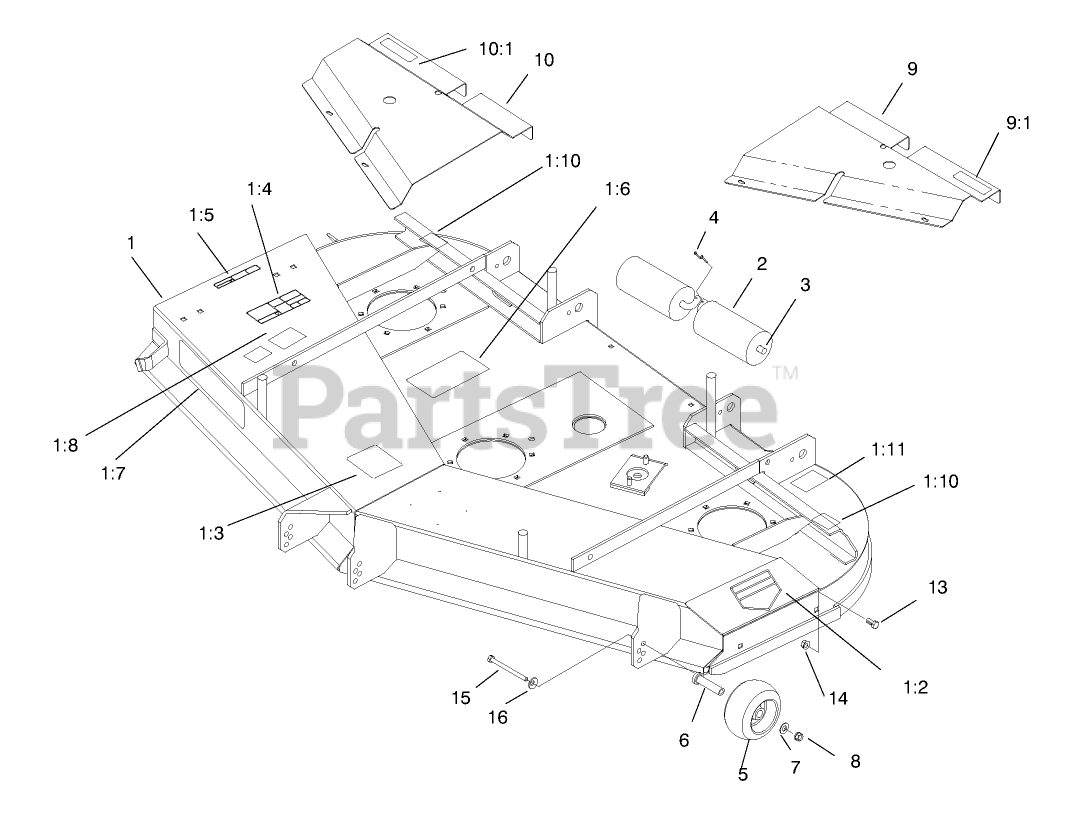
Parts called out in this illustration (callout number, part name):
1	62" DECK ASM W/DECALS
1:2	DECAL-DANGER
1:3	DECAL-WHEEL, GAGE
1:4	DECAL-DANGER, THROWN OBJECT
1:5	DECAL-DANGER
1:6	DECAL-BELT ROUTING
1:7	DECAL - 62 INCH DECK
1:8	DECAL
1:10	DECAL-COVER, MISSING
1:11	DECAL-TORQUE, BLADE BOLT
2	ROLLER-DECK
3	SHAFT-ROLLER, REAR
4	PIN-COTTER
5	WHEEL-GAGE
6	SPACER-WHEEL
7	WASHER-FLAT
8	NUT-LOCK, NI
9	LH COVER ASM
9:2	DECAL-DANGER
10	RH COVER ASM
10:2	DECAL-DANGER
13	SCREW-HH
14	NUT-HHF, WHIZ
15	SCREW-HH
16	WASHER-BELLEVILLE
